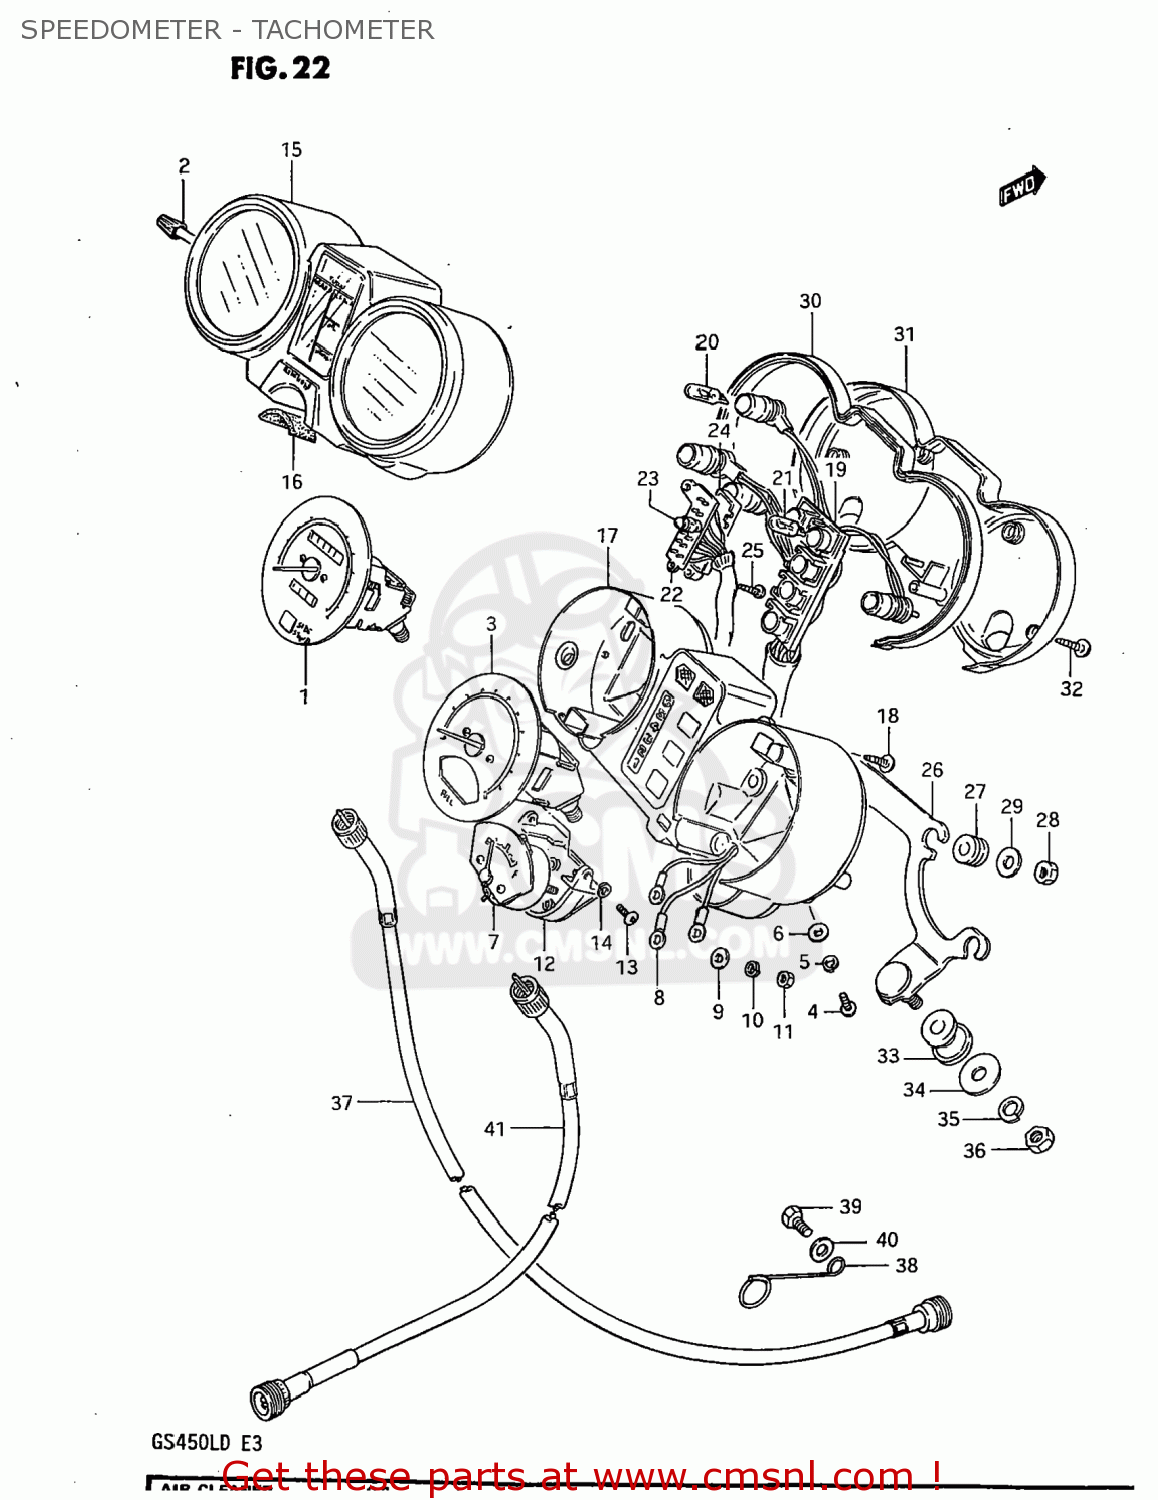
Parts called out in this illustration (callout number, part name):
1	METER,SPEEDOMETER (KM/MPH)
2	KNOB
3	TACHOMETER
4	SCREW 4X10
5	WASHER
6	LOCK WASHER
7	METER,FUEL
8	WIRE,FUEL METER LEAD
9	WASHER,FUEL METER
10	LOCK WASHER
11	NUT 3MM
12	BRACKET,FUEL METER
13	SCREW
14	LOCK WASHER
15	HOOD,METER
16	SEAL,IGNITION SWITCH
17	CASE,METER,INNER
18	SCREW
19	SOCKET,METER
20	BULB(12V3.4W,T10)
21	BULB(12V1.7W,T10,WB121)
22	SOCKET,GEAR INDICATOR
23	BULB(14V1.12W,BQ041-32503B)
24	COVER,INDICATOR,LOWER
25	SCREW
26	BRACKET,COMBINATION METER
27	CUSHION,METER
28	NUT
29	WASHER (5.5X16X1.2)
30	COVER,METER,UNDER
31	COVER,LWR
32	SCREW
33	CUSHION,METER BRACKET
34	WASHER (8.5X29X1.6)
35	LOCK WASHER
36	NUT
37	CABLE ASSEMBLY,SPEEDOMETER
38	CLAMP,SPEEDOMETER CABLE
39	BOLT, UPPER
40	WASHER
41	CABLE ASSEMBLY,TACHOMETER
